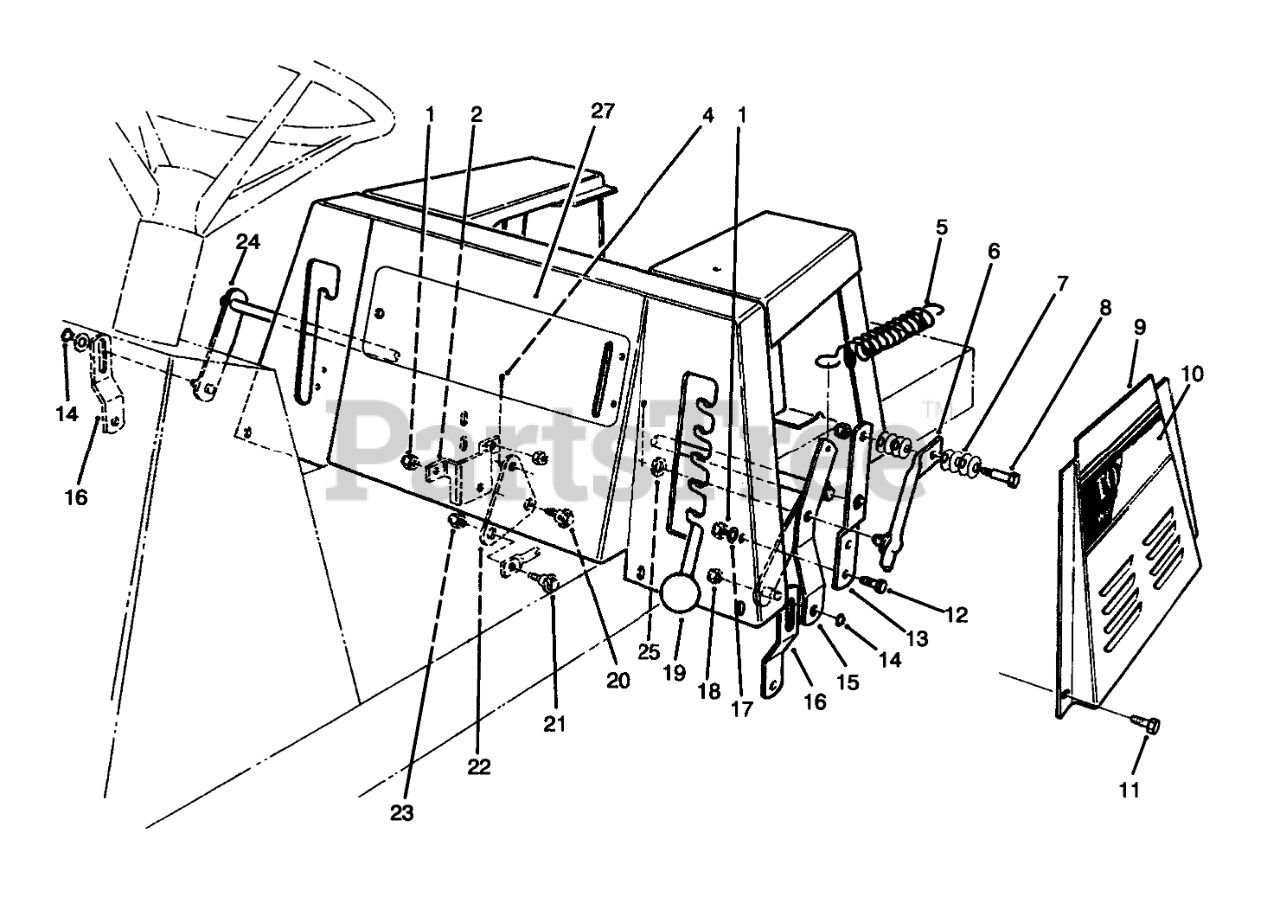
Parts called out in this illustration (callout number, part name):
1	NUT-LOCK, NI
2	BRKT-B.CRANK MTG
4	PIN-COTTER
5	SPRING-EXTENSION
6	HOC LEVER WA B
7	WASHER-BELLEVILLE
8	BOLT-SHOULDER
9	Panel L.H.-Base, Seat
10	DECAL - TORO 1232 LH
10	DECAL - TORO 1032 LH
11	SCREW-HH
12	SCREW-HH
13	Bracket
14	RING-RETAINING
15	Bracket-H.O.C., Engage
16	Link-Deck Suspension
17	WASHER-PLAIN
18	NUT-LOCK, NI
20	SCREW-SHOULDER
21	SCREW-SHOULDER
22	BELLCRANK
23	NUT-HEX
24	Arm
25	WASHER-FLAT
27	DECAL - CONTROL PANEL
